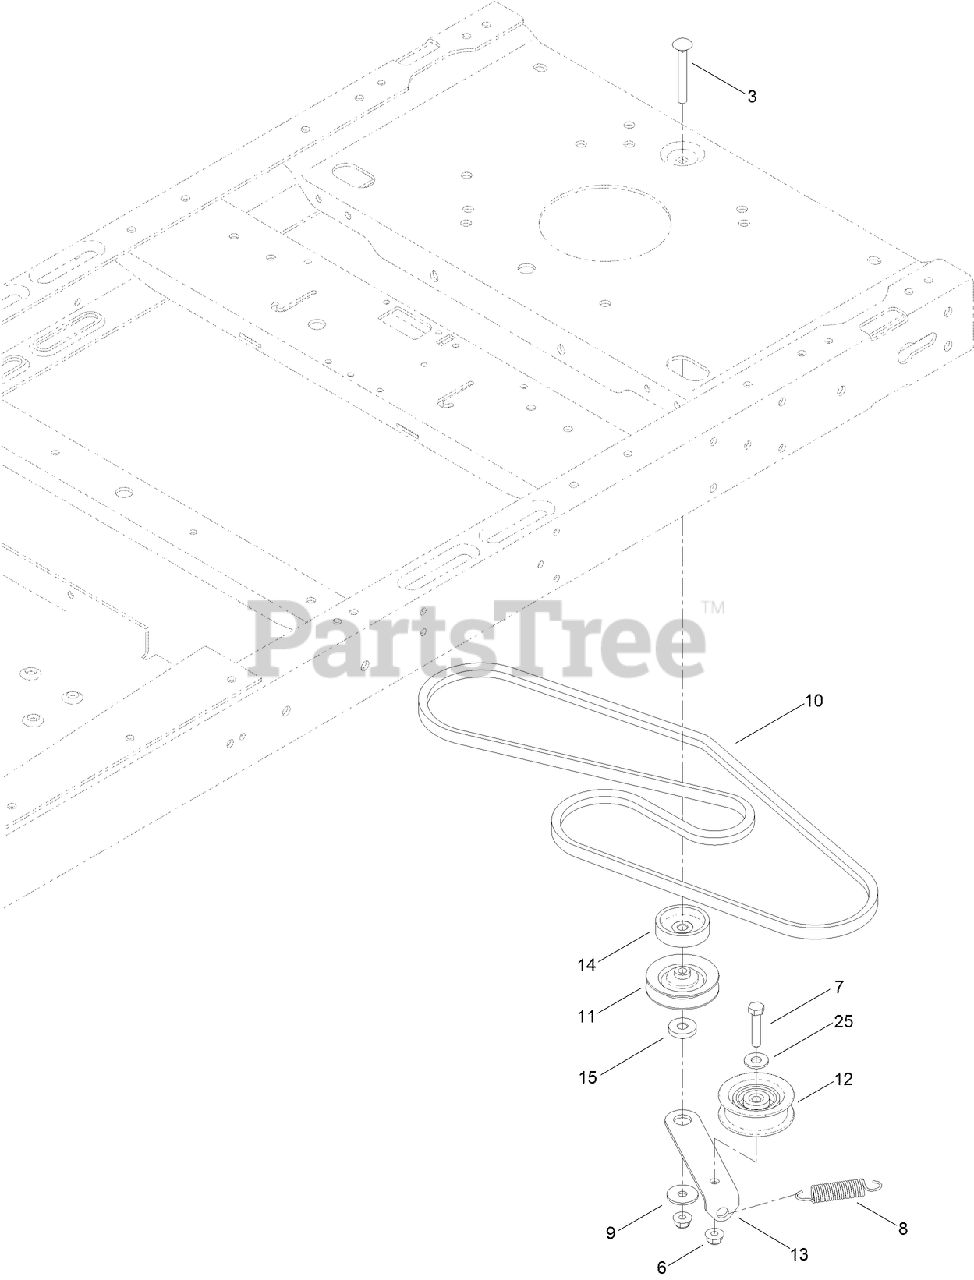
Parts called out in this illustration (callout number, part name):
3	SCREW-CARR
6	NUT-HF, NI
7	SCREW-HH
8	SPRING-RETURN, PEDAL
9	WASHER-PIVOT
10	V-BELT
11	PULLEY-IDLER
12	PULLEY-IDLER
13	ARM-IDLER
14	SPACER
15	SPACER-ARM, IDLER
25	WASHER-FLAT
